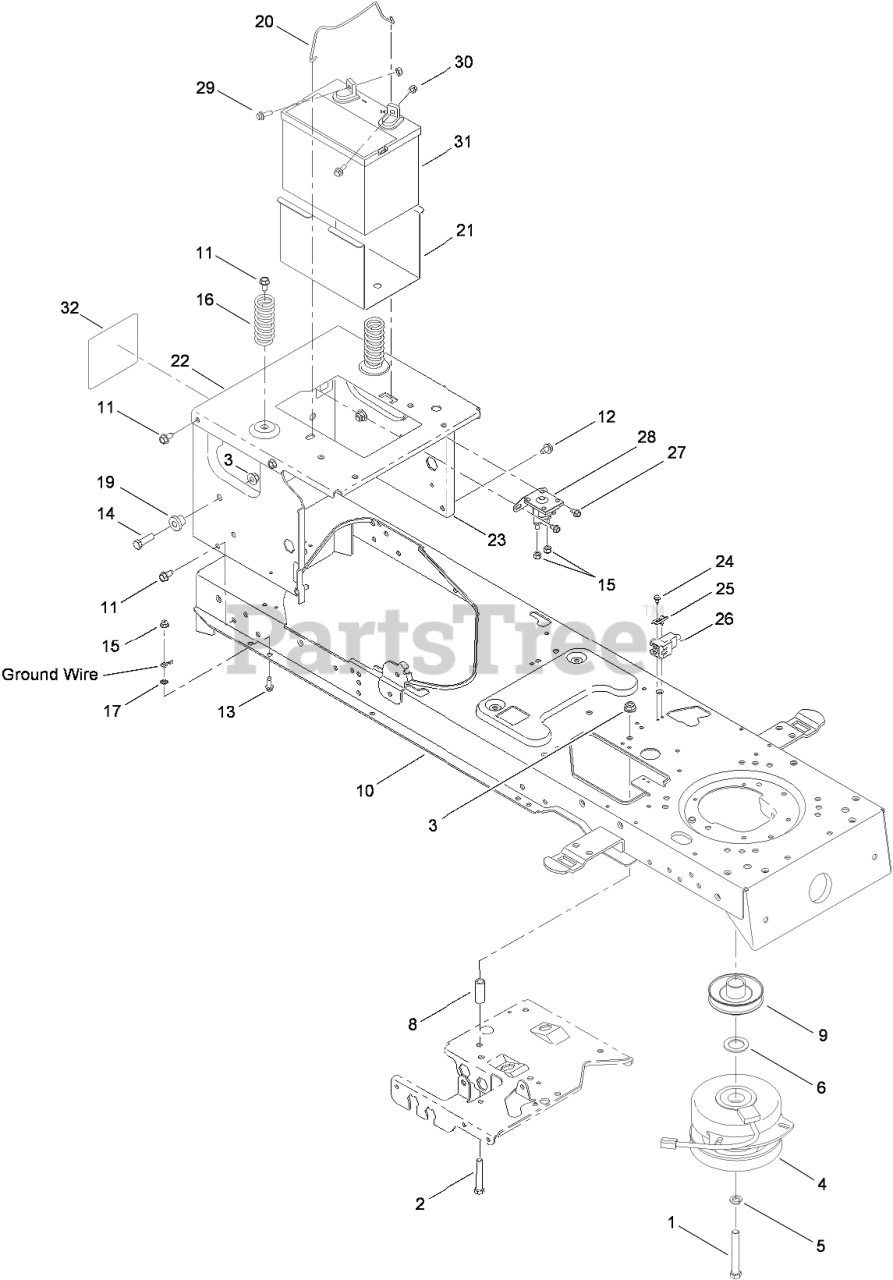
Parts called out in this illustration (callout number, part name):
1	SCREW-HH
2	SCREW-HH
3	NUT-LOCK, FLANGE
4	CLUTCH-ELECTRIC
5	WASHER-LOCK
6	WASHER-FLAT
8	SPACER
9	PULLEY-ENGINE
10	LOWER FRAME ASM
11	SCREW-TAP
12	SCREW-TAP
13	SCREW-TAP
14	SCREW-HH
15	NUT-LOCK, FLANGE
16	SPRING-COMPRESSION
17	WASHER-LOCK, EXTERNAL
19	SPACER-SHOULDER
20	ROD-HOLDDOWN, BATTERY
21	TRAY-BATTERY
22	BRACKET-FRAME, SEAT
23	FRAME-UPPER
24	SCREW-TAP
25	PLATE-SWITCH
26	SWITCH-INTERLOCK
27	SCREW-HWHTF
28	SOLENOID-12V, 2 POST 2 Tab
29	BOLT-CARRIAGE
30	NUT-SEMS
31	BATTERY-245, CCA (DRY FLAT TOP)
32	DECAL-TORO
